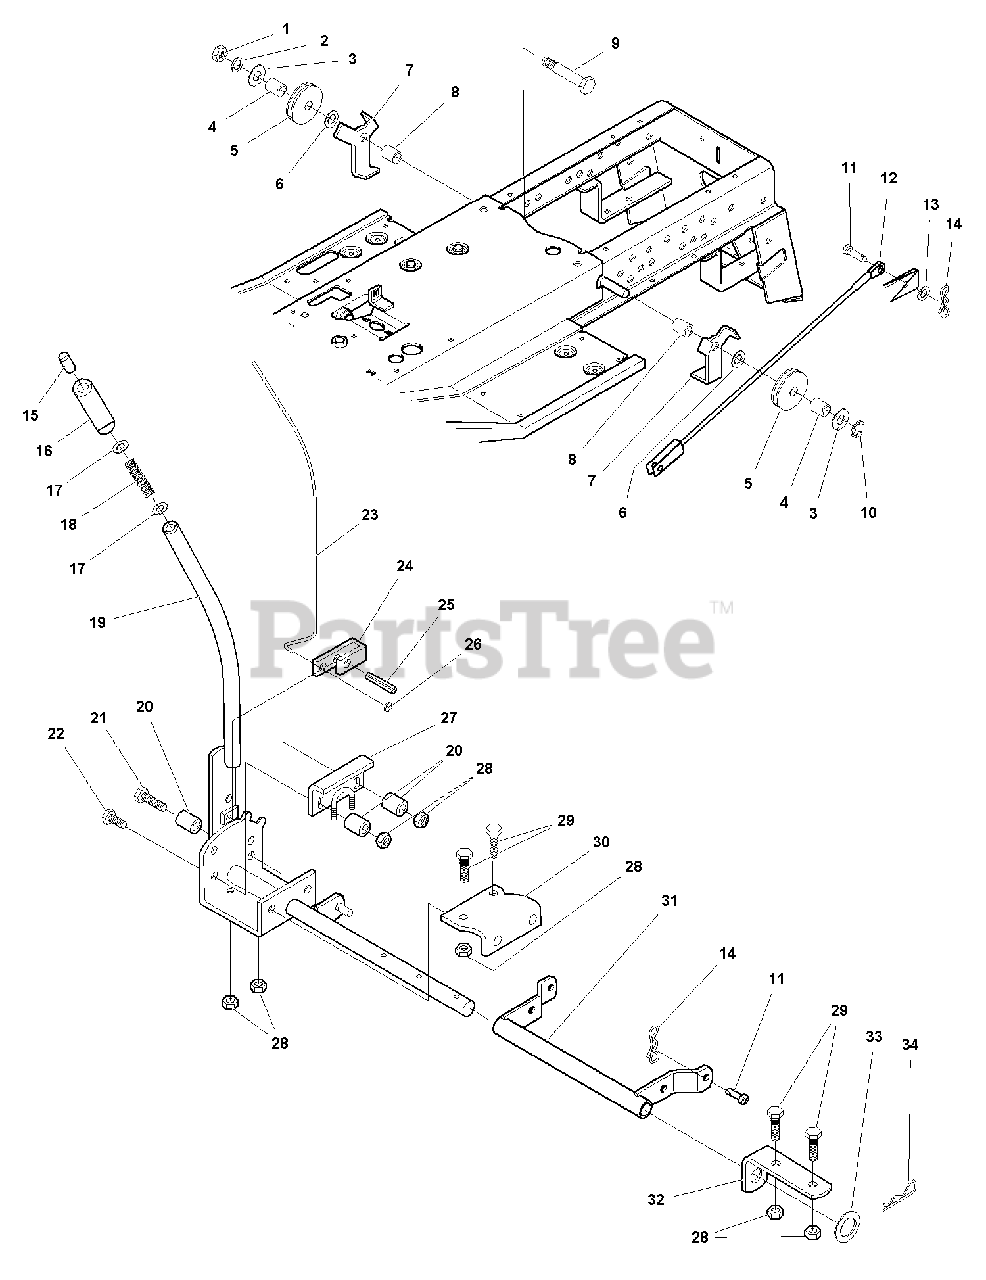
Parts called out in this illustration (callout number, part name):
1	NUT, 1/2-13
2	WASHER, Lock, 1/2-13
3	WASHER, 1/2
6	WASHER, 1/2
7	PULLEY, Guide
9	CAPSCREW, Hex Head, 1/2-13 x 3
10	RING, Klipring
11	PIN, Round Head, Drilled, 3/8 x 1
13	WASHER, 3/8
14	PIN, Cotter Locking
16	GRIP, Black
17	WASHER, 5/16
18	SPRING, Compression
19	QUADRANT & LEVER ASSEMBLY
21	CAPSCREW, Hex Head, 5/16-18 x 1-3/4
22	CAPSCREW, Hex Head, 5/16-18 x 1-1/4
24	LATCH
25	ROLL PIN, 3/8 x 1
26	PUSH NUT, 5/16
27	BRACKET & U BOLT ASSEMBLY (Early Models)
27	BRACKET & U BOLT ASSEMBLY (Later Models)
28	LOCKNUT, 5/16-18
29	CAPSCREW, Hex Head, 5/16-18 x 7/8
30	BRACKET & PINS ASEMBLY
31	TUBE & ARMS ASSEMBLY
33	WASHER, 3/4
